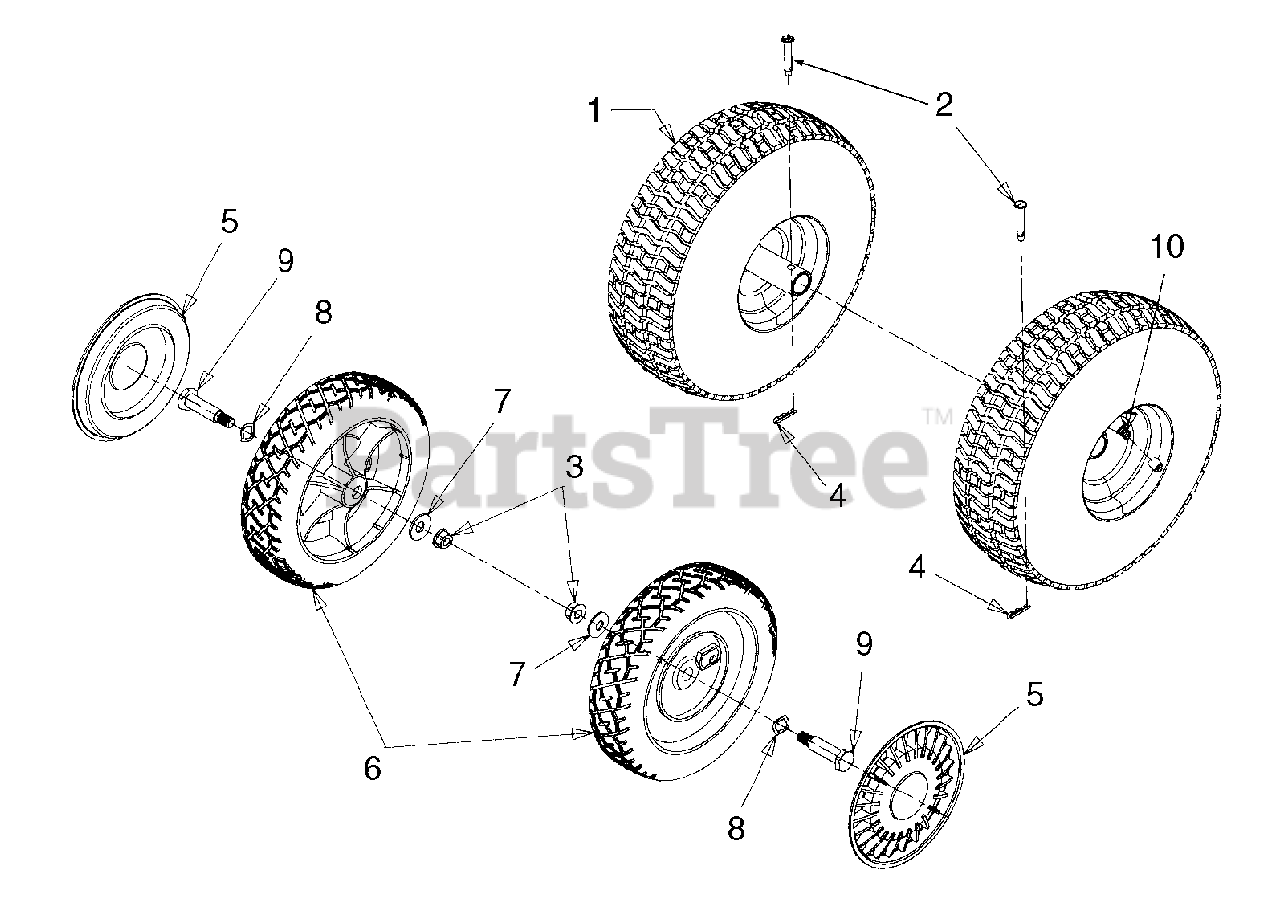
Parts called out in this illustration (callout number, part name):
1	Wheel Ass,y Complete
2	Pin, Clevis, .25 x 1.53
3	Nut, Hex Flange Lock, 3/8-16
4	Pin, Internal Cotter
5	Hubcap, Beige
6	Wheel Ass'y Complete, 8 x 2.0
7	Washer, Bell, .401 x .870 x .06
8	Washer, Wave, .53 x .78 x .013
9	Shoulder Bolt
10	Valve, Tubeless Air
